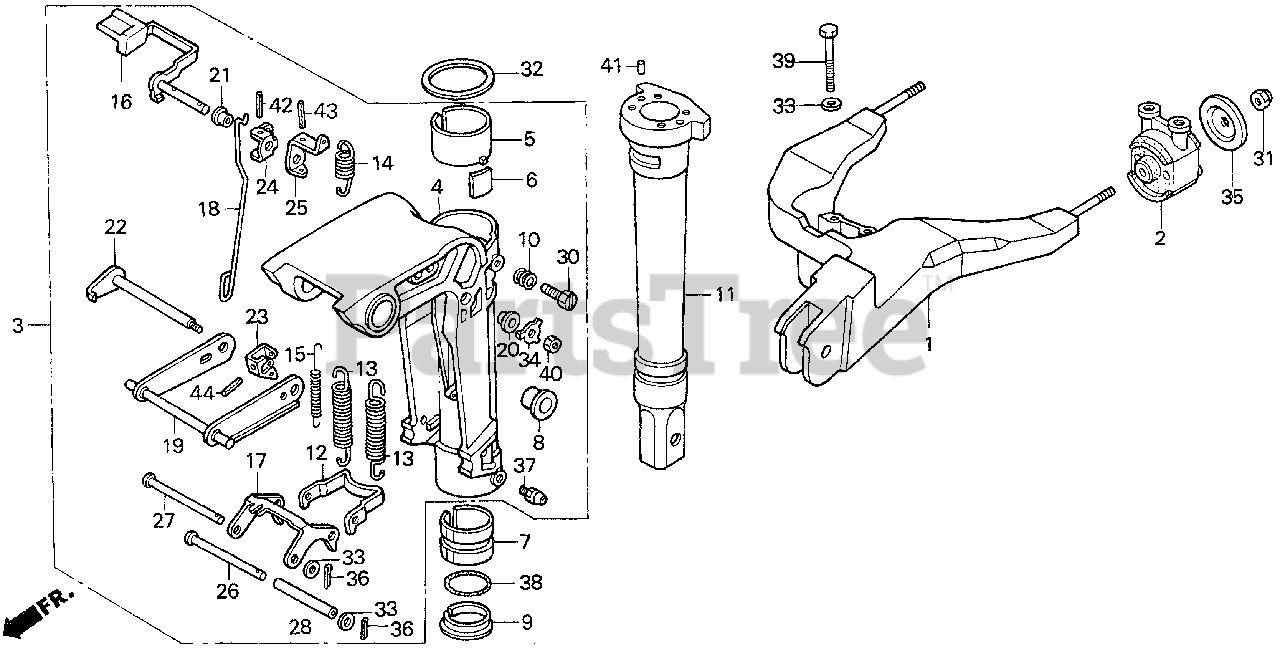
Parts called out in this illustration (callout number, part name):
1	FRAME, MOUNTING *NH282MU* (OYSTER SILVER METALLIC-U)
2	MOUNT, RUBBER (UPPER) *NH282MU* (OYSTER SILVER METALLIC-U)
3	CASE ASSY., SWIVEL *NH282MU* (OYSTER SILVER METALLIC-U)
4	CASE, SWIVEL *NH282MU* (OYSTER SILVER METALLIC-U)
5	LINER, SWIVEL CASE
6	BLOCK, FRICTION
7	BUSH, SWIVEL SHAFT
8	BUSH, SWIVEL CASE
9	COLLAR, SWIVEL CASE
10	SPRING, FRICTION ADJUSTING
11	SHAFT, SWIVEL *NH282MU* (OYSTER SILVER METALLIC-U)
12	HOOK, REVERSE LOCK
13	SPRING, REVERSE LOCK
14	SPRING, TILT LEVER
15	SPRING, TILT LINK
16	LEVER, TILT
17	ARM, REVERSE LOCK
18	ROD, RELEASE SWIVEL CASE
19	ARM, TILT
20	BUSH, TILT LEVER
21	BUSH, TILT LEVER
22	SHAFT, TILT
23	BRACKET, TILT SHAFT
24	BRACKET, RELEASE ROD
25	BRACKET, TILT LEVER
26	SHAFT, REVERSE LOCK (A)
27	SHAFT, REVERSE LOCK (B)
28	COLLAR, REVERSE LOCK
30	BOLT, SPECIAL (8X20)
31	NUT, SELF-LOCK (8MM)
32	WASHER, THRUST (51MM)
33	WASHER, PLAIN (6MM)
34	WASHER, LOCK
35	WASHER, PLAIN (8MM)
36	PIN, SPLIT (2.0)
37	NIPPLE, GREASE
38	O-RING (39.5X2.4) (ARAI)
39	BOLT, HEX. (6X45)
39	BOLT, HEX. (6X60)
40	NUT, HEX. (6MM)
41	PIN, DOWEL (6X10)
42	PIN, SPRING (2.5X22)
43	PIN, SPRING (2.5X25)
44	PIN, SPRING (3X25)
